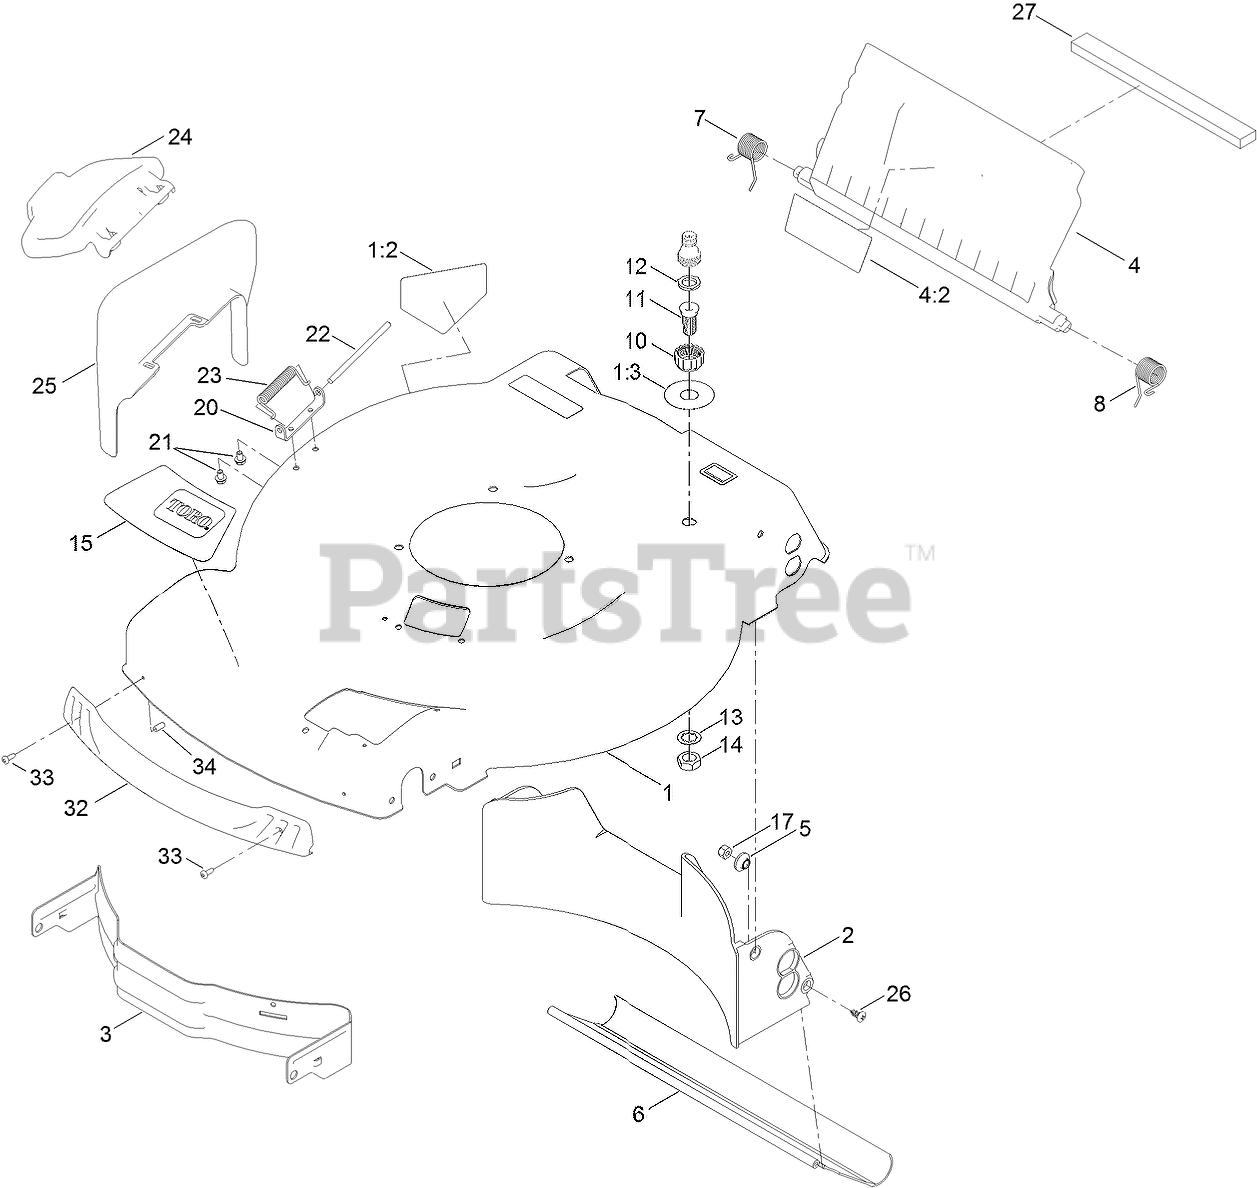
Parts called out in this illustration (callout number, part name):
1	HOUSING ASM
1:2	DECAL-DANGER
1:3	DECAL-QUICK WASH
2	BAFFLE-REAR
3	BAFFLE-FRONT
4	REAR DEFLECTOR ASM
4:2	DECAL-WARNING
5	WASHER-STEPPED, BAFFLE
6	SHIELD-TRAILING
7	SPRING-TORSION
8	SPRING-TORSION
10	COUPLING-HOSE, WASHOUT PORT
11	PORT-WASHOUT
12	WASHER-SEAL, WASHOUT PORT
13	WASHER-LOCK
14	NUT-JAM
15	DECAL-RECYCLER
17	NUT-LOCK, NI
20	BRACKET-COVER
21	SCREW-HWH
23	SPRING-TORSION
24	DEFLECTOR-SIDE
25	CHUTE-DISCHARGE, SIDE
26	SCREW-PTH
27	FOAM-SEAL
32	BUMPER
33	SCREW-FORMING, THREAD
34	CAP-PLUG
